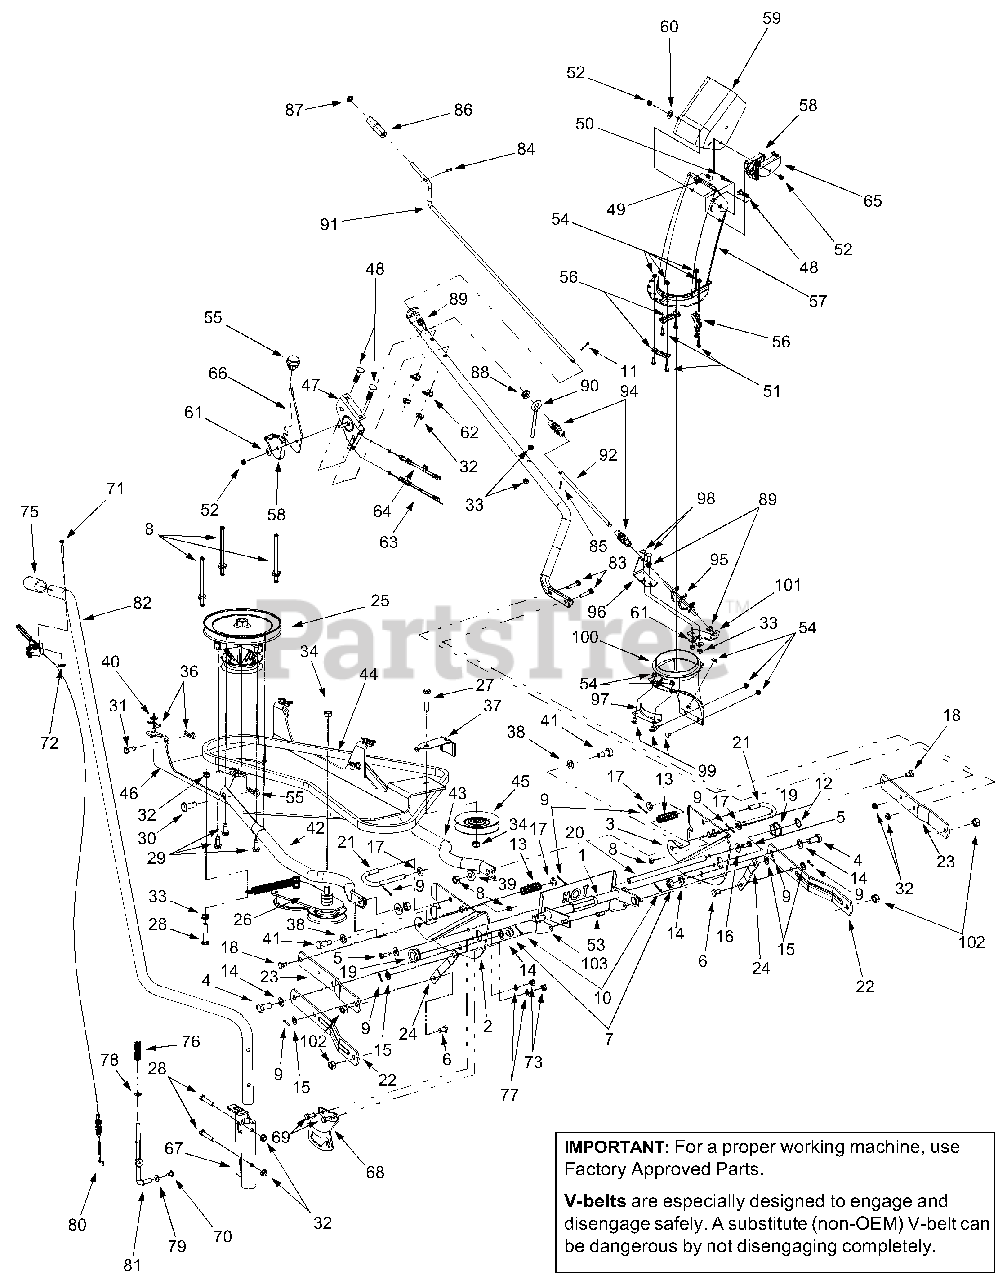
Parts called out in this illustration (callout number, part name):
1	Rod Assembly
4	Hex Cap Screw, 5/8-18 x 1.31
5	Hex Cap Screw, 3/8-16 x 1.0
6	Clevis Pin, .5 x .78
7	Slotted Hex Nut, 5/8-18
8	Belt Keeper Pin
9	Cotter Pin, .125 x .75
10	Cotter Pin, 1/8 x 1.25
11	Cotter Pin
12	Snap Ring
13	Compression Spring, .72 x 2.25
14	Flat Washer, .64 x 1.12 x .125
15	Flat Washer, .51 x 1.0 x .060
16	Bell Washer, .396 x 1.14 x .095
17	Flat Washer, .531 x .875 x .15
18	Shoulder Screw, .5 x .29, 3/8-16
19	Flange Bearing w/ Flats
20	Rod, 1/2 x 11.55
21	Handle Rod
22	Link, 15.3
23	Link, 13.25
25	Spindle Assembly
26	Double-idler Bracket Assembly
27	Hex Cap Screw, 3/8-16 x 1.75
28	Hex Cap Screw, 5/16-18 x 1.75
29	Self Tapping Screw, 5/16-18 x .75
30	Clevis Pin, .5 x 1.18
31	Clevis Pin, 3/8 x .75
32	Flange Lock Nut, 5/16-18
33	Hex Nut, 5/16-18
34	Hex Flange Lock Nut, 3/8-24
35	Internal Cotter Pin, .125 x 1.75
36	Click Pin, .092 x 1.64
37	Belt Guard
38	Flat Washer, .531 x .93 x .09
39	Flat Washer, .38 x .93 x .11
40	Flat Washer, .344 x .688 x .065
41	Shoulder Screw, 3/8-16, .5 x .835,
42	RH Support Tube
43	LH Support Tube
44	Upper V-belt
45	Idler Pulley, 3.5" Diameter
48	Carraige Bolt, 5/16-18 x 1.5
49	Carraige Bolt, 5/16-18 x .75
50	Hex Index Washer Screw, 1/4-14 x .625
51	Hex Cap Screw, 1/4-20 x .75
52	Nylon Hex Lock Nut, 5/16-18
53	Hex Cap Screw, 5/16-18 x .75
54	Hex Flange Lock Nut, 1/4-20
56	Chute Flange Keeper
57	Lower Chute
58	Chute Tilt Cable Guide
59	Upper Chute
60	Flat Washer, .344 x 1.125 x .125
61	Bell Washer, .34 x .872
62	Saddle Washer, .32 x .93
63	Chute Cable, 62"
64	Chute Cable w/ Clip, 62"
66	Chute Tilt Handle
70	Hex Index Washer Screw #10-16 x .375
71	Pan Phillips Screw, #10-24 x .75
72	Flat Weld Nut, #10-24
73	Hex Nut, 5/16-24
74	Heavy Duty Spirol Pin, 1/4 x 1.5
75	Handle Grip
76	Compression Spring, .406 x .531 x 1.75
77	Lock Washer, 5/16
78	Flat Washer, .385 x .62 x .063
79	Flat Washer, .194 x .62 x .063
80	Lift Cable, 42" w/ Trigger Control
81	Lift Index Rod
83	Hex Cap Screw, 5/16-18 x 1.5
84	Rolled Pin, 1/8 x .63
85	Spirol Pin, .125 x .82
86	Crank Knob
87	Push Cap, 3/8 ID
88	Rubber Grommet , .44 x .94 x .5
89	Plastic Bushing
90	Eye Bolt
91	Chute Crank Rod, .375 x 33
92	Rod, .375 x 11.375
93	Support Chute Tube
94	Joint Block Assembly
95	Chute Crank Assembly
98	Splined Carriage Screw, 5/16-18 x 1.0
99	Carriage Screw, 1/4-20 x .5
100	Adapter Chute
101	Chute Crank Bracket
102	Hex Lock Nut, 1/2-13
103	Heat Shield
